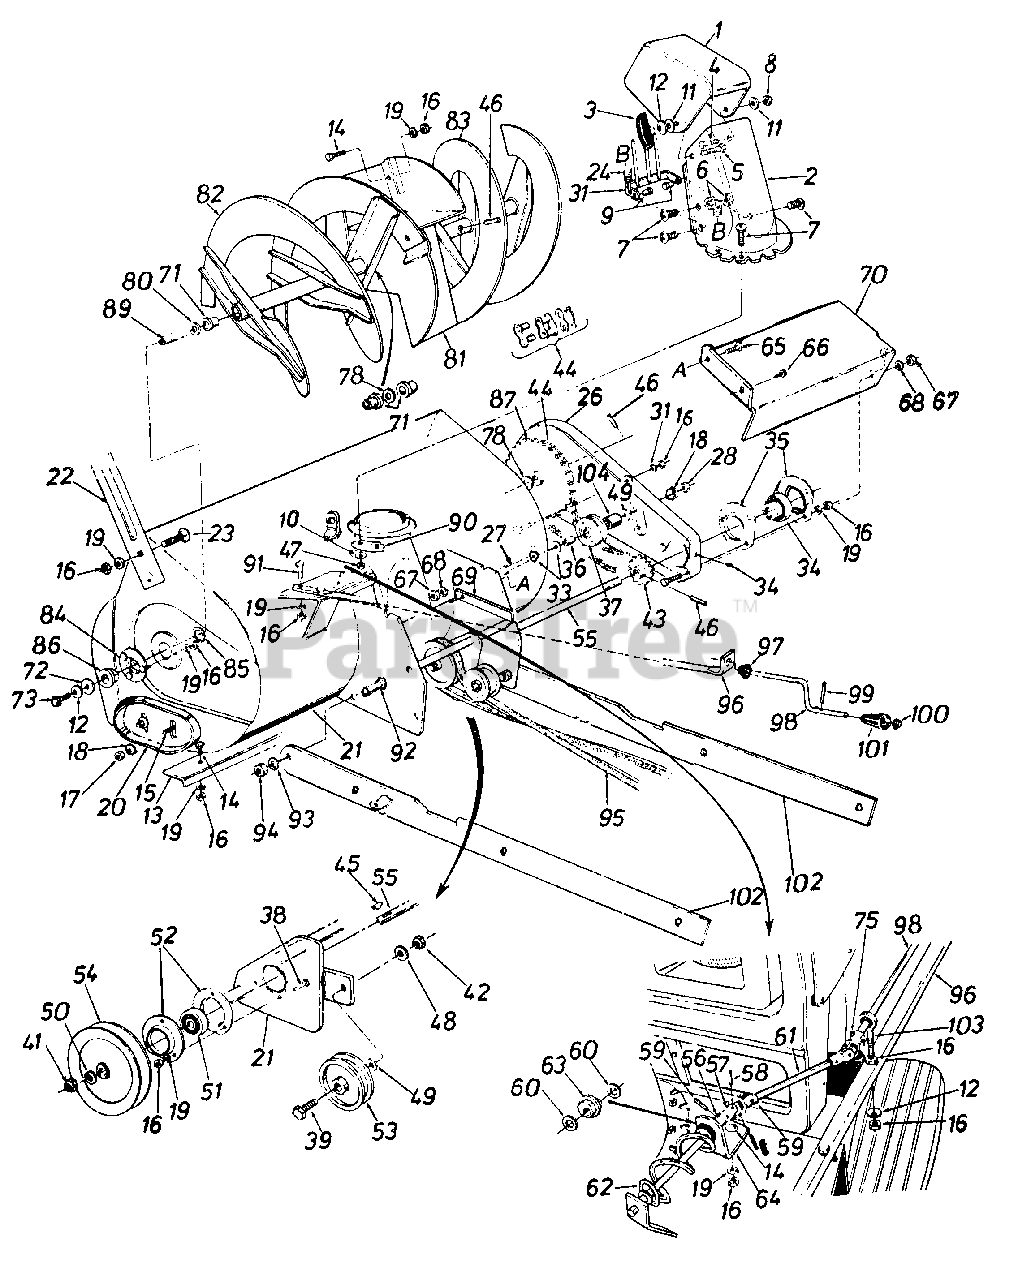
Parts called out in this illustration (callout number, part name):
1	Upper Chute
2	Lower Chute
3	Knob Handle Ass'y.
4	Truss Mach. Scr. 5/16-18 x .75" Lg.
5	Carriage Bolt 5/16-18 x 1.0"*
6	Hex Cent. L-Nut 5/16-18 Thd.
7	Truss Mach. Scr. 1/4-20 x .75" Lg.
8	Hex Cent L Nut 5/16-18 Thd.
9	Shld. Nut 14-20 Thd.
10	Fl. Wash. 1/4" I.D.
11	Fl.-Wash. .344" I.D. x 1.125"
12	Bell. Wash. .345" I.D. x .88"
14	Carriage Bolt 5/16-18 x .62"
15	Carriage Bolt 3/8-16 x .62"*
16	Hex Nut 5/16-18 Thd.*
17	Hex Jam Nut 3/8-16 Thd.
18	Bell. Wash. .40 I.D. x .88"
19	L.-Wash. 5/16" I.D.*
20	Slide Shoe
21	Spiral Hsg. Ass'y.-36
22	Guide Blade
23	Carriage Bolt 5/16-18 x .62"*
24	Extension Spring
26	Chain Guard Ass'y.
27	Hex Bolt 3/8-16 x 2.00 Lg.*
28	Hex Inst.-Nut 3/8-16 Thd.
33	Fl.-Wash. .385" I.D. x .87" O.D.
34	Ball Brg. .75" I.D.
35	Flangette
36	Spacer .375" I.D. x .60" O.D.
37	Fl.-Idler w/Flanges 1.875
38	Hex Sems Bolt 5/18x.75" Lg.
39	Hex Bolt 3/8-16 x 1.75" Lg.*
41	Hex Jam Nut 3/4-10 Thd.
42	Hex Jam Nut 3/8-16 Thd.
43	Sprocket Ass'y.-14 Teeth
44	#420 Chain x 1/2" Pitch - 77 Links
45	61 Hi-Pro-Key 3/16 x 5/8"
46	Spring Pin Spir. 5/16" Dia. x 1.75" Lg.
47	Hex L-Nut 1/4-20 Thd.
48	L.-Wash. 3/8" I.D.*
49	Fl.-Wash. .406" I.D. x 1.25"
50	Spring L.-Wash. 3/4" I.D.
51	Self-Aligning Brg.
52	Flangette
53	Idler Pulley
54	5/8 V Pulley .75" I.D. x 6"
55	Drive Shaft Ass'y
56	Joint Brkt. Ass'y.
57	Jolnt Block
58	Oval Head Rivet
59	Spiral Pin 1/8" Dia.
60	Fl-Wash. .385" I.D. x .62"
61	Chute Crank Ext. Rod
62	Chute Crank Ass'y. R.H.
63	Plastic Bushil-g .380" I.D.
64	Chute Crank Brkt.
65	Hex Bolt 1/4-20 x .62" Lg.
66	Hex Wash. S-Tap Scr. 1/4-2C x . 50 Lg.
67	Hex Nut 1/4-20 Thd.*
68	L.-Wash. 1 4" I.D.*
69	Belt Cover
70	Drive Shaft Cover
71	Plastic Bushing
72	Washer .39" I.D. x 1.75" O.D
73	Hex Bolt 5/16-18 x .88" Spec
75	Cotter Pin 3/32" Dia.
78	Fl.-Wash. 1.03" I.D. x 1.62"
80	Fl.-Wash. 1.0" x 1.75"
85	Snap Ring for 1.50" Shaft
86	Flange Brg. w/flats 1.00" I.D.
87	Sprocket Hub Ass.y. 40 Teet
89	Spiral Axle
90	Chute Flange Keeper
91	Hex Bolt 5/16-18 x 1.5" Ly.
92	Hex Bolt 1/2-13 x 1.25" Ls.-'
93	L.-Wash. 1/2" I.D.
94	Hex Nut 1/2"13 Th
95	"V"Belt
98	Chute Crank 34.5" L.g
99	Roll Pin .12 Dia. x .63
100	Push Nut 3/8" Rod
101	Knob Black
102	Linkage Arm
103	Eye Bolt 5/16-18 x 3.0" Lg.
104	Idler Spacer
